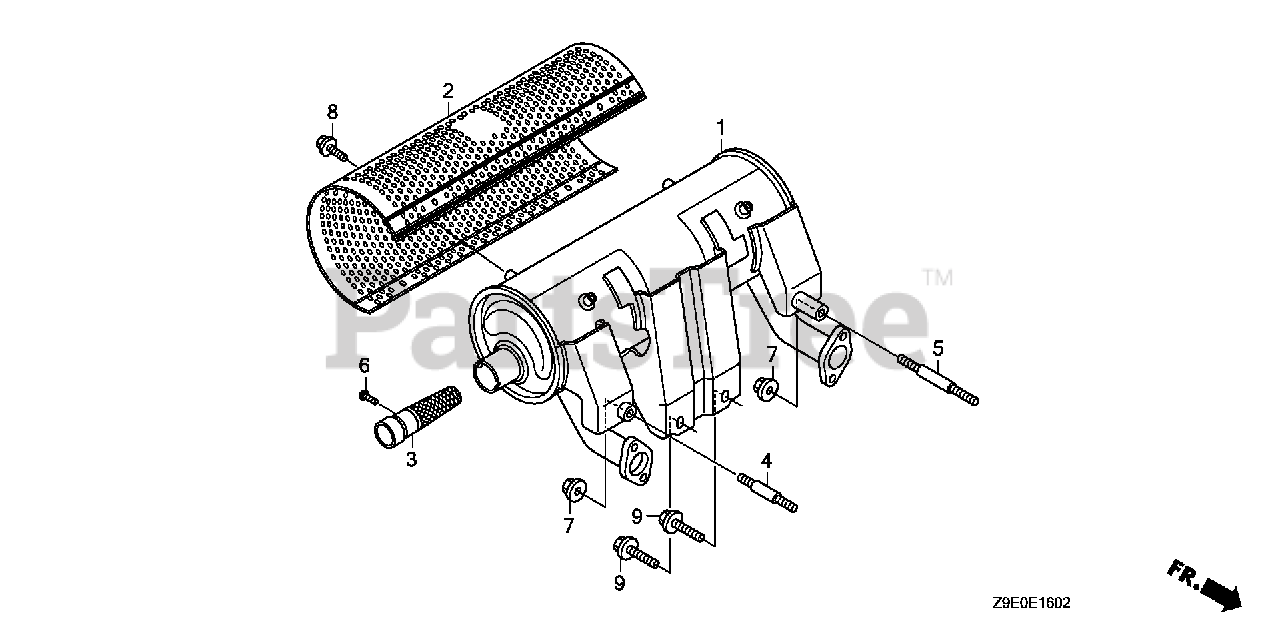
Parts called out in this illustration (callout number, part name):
1	MUFFLER (HIGH-R)
2	PROTECTOR, MUFFLER (HIGH) (FUTABA)
3	ARRESTER KIT (HIGH)
4	BOLT, STUD (8X45)
5	BOLT, STUD (8X60)
6	SCREW, TAPPING (5X8)
7	NUT, FLANGE (8MM)
8	BOLT, FLANGE (6X8)
9	BOLT, FLANGE (8X20)
